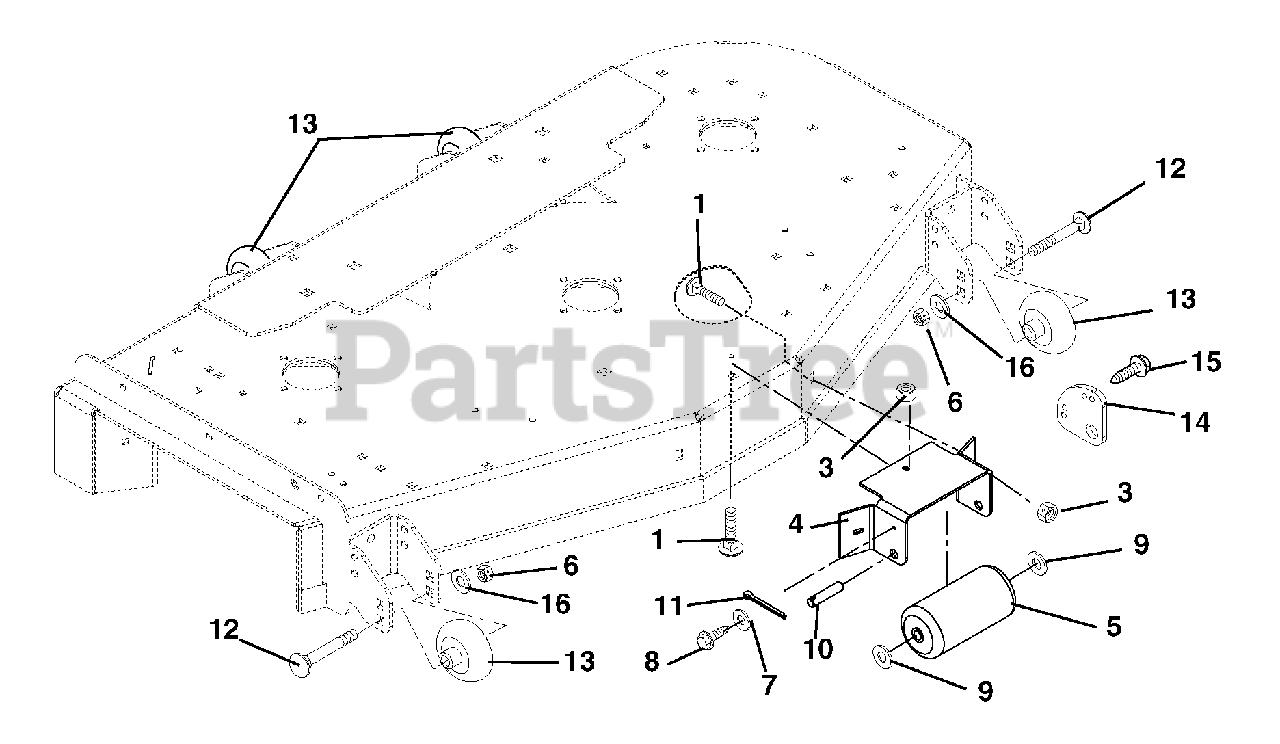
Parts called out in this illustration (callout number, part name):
1	Bolt, Round Head Square Neck .38-16 x 1.00 Grade 5 (042, 043, 044, 054, 310, 311)
2	Bolt, Round Head Square Neck .38-16 x 1.25 Grade 2 (051, 055)
3	Nut, Locking Top Flange .38-16
4	Bracket, Anti-Scalp Roller (043, 044, 054, 311)
4	Bracket, Anti-Scalp Roller (051, 055)
4	Bracket, Anti-Scalp Roller (042, 310)
6	Nut, Locking Nylon .50-13
7	Washer, Flat Steel .281 x .62 x .065
8	Screw, Tapping .25-20 x .75 Hex Washer Head
9	Washer, Flat Steel .656 x 1.31 x .095
11	Pin, Cotter .25 x 2.0
12	Bolt, Round Head Square Neck .50-13 x 5.00 Grade 2
13	Wheel, 3 x 5
14	Anti-Scalp Washer
15	Screw, Tapping .25-20 x .62 Hex Washer Head
16	Washer, Flat Steel .531 x 1.06 x .095
